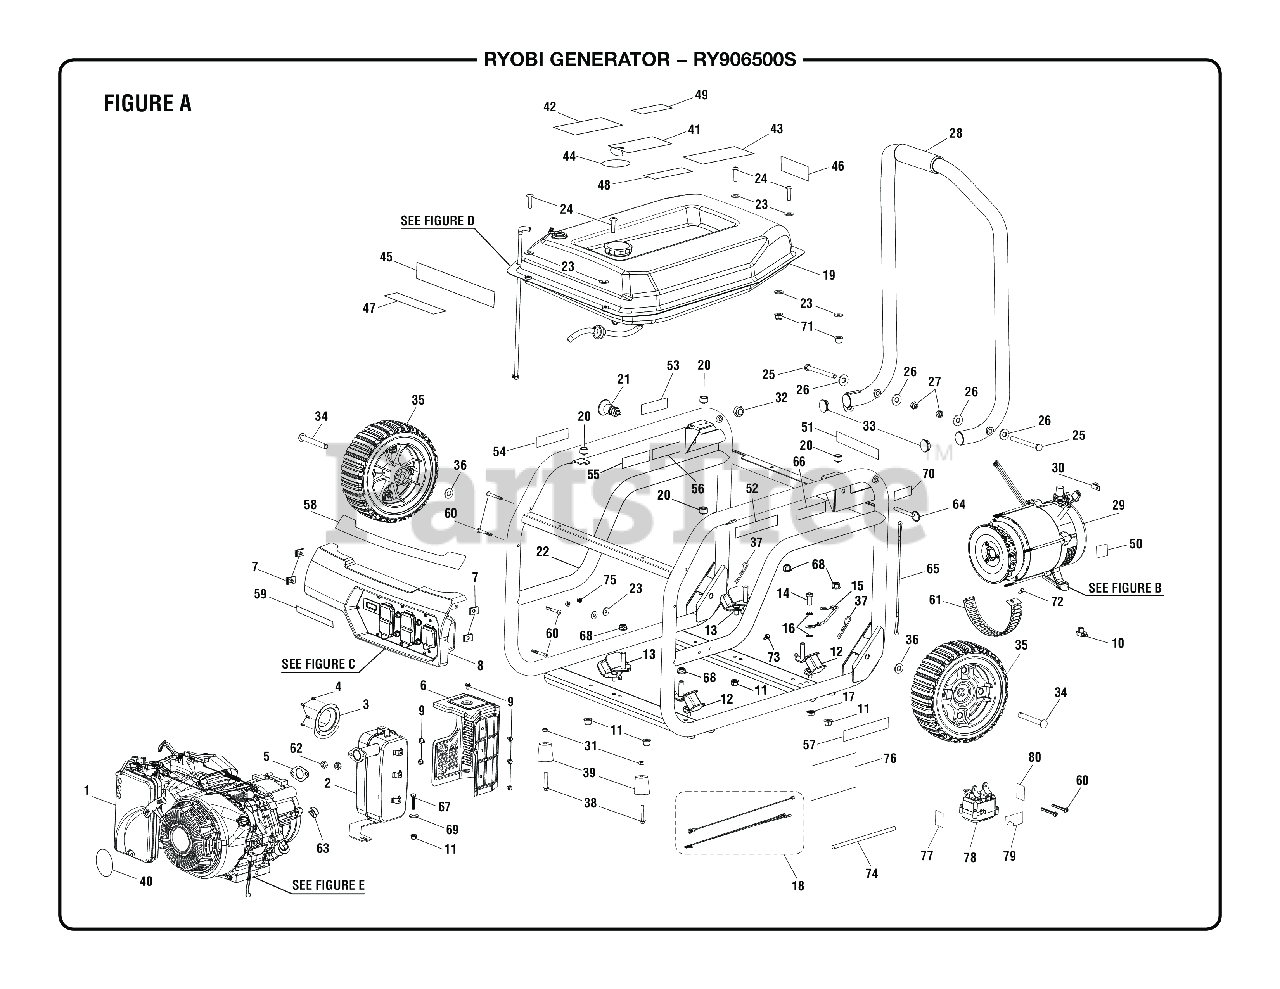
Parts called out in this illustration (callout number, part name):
3	Spark Arrester Screen
4	Screw (8-32 x 3/8 in., Pan Hd.)
5	Exhaust Gasket
6	Heat Shield
7	U-Clip (M6)
8	Control Panel Assembly
9	Bolt (M6 x 9 mm, Hex Flange Hd.)
10	Rubber Wire Protector
11	Lock Nut (M8 x 1.25 mm, Flange)
12	Engine Isolator (Large)
13	Engine Isolator (Right)
14	Bolt (5/16-18 x 3/4 in., Hex. Hd.)
15	Assembly, ground wire
16	Washer (5/16 in., External Star)
17	Flange Nut (5/16-18, Hex Hd.)
18	Wire Assembly
19	Fuel System
20	Handle Bumper
21	Quick Release Pin Assembly
22	Carrier Assembly
23	Washer (1/4 in., Type A)
24	Screw (1/4-20 x 1 in., T30 Torx Hd.)
25	Handle Pivot Pin (5/6-18 x 90 mm)
26	Washer ( 5/16 in.)
27	Lock Nut (5/16-18, Hex Hd.)
28	Handle Assembly
29	Generator Head Assembly
30	Ground Lug (5/16-24) (BM903600)
31	Lock Nut (M8 x 1.25)
32	Lock Nut (1/2-20, Hex)
33	End Cap (Handle)
34	Washer (M10)
35	Handle Isolator
36	Washer (OD19.75 x ID10.5 x 1t)
37	Hitch Pin (M3)
38	Bolt (M8 x 1.25 in., Flange Hex Hd.)
39	Foot Assembly
40	Engine Recoil Label
41	Warning Hangtag
42	Warning Label
43	CPSC (English) Label
44	Remove Cap Fuel Stabilizer Label (English)
45	Logo Label
46	UL Fire Warning Label Spark Arrestor)
47	Start Label
48	Fuel Stabilizer Label (French/Spanish)
49	No E85 Label
50	Ground Label Icon
51	Ground Warning Label
52	Risk of Fire Danger Label
53	Quick Release Pin Label
54	Exhaust Direction Label
55	Hot Surface and Exhaust Label
56	Fire Distance Label (Eng/Sp)
57	Engine Lubricant Label
58	Performance Label
59	Choke Label
60	Screw (M6 x 50 mm, T30 Torx Pan Hd. )
61	Fan Cover (Generator Head)
62	Hex Nut (M8 x 1.25, Special)
63	Plug (Generator Head)
64	Release Pin (5/16 x 2 in.)
65	Lanyard (3/16 in.)
66	Inquires Label (Ryobi)
67	Screw (M8 x 40 mm, Hex Hd.)
68	Lock Nut (5/16-18)
69	Washer (ID9 x OD25.4 x 2t)
70	Lock Pin Label
71	NYLON LOCK NUT (1/4-20)
72	Screw (M5 x 10 mm, Hex Hd.)
73	Bolt (M5 x 10 mm, Flange Hex Hd.)
74	Heat Shrink Tube
75	Lock Nut (M6 x 1 mm)
76	Auto Shut-Off Hang Tag
77	CO Shut-Off Label (English/Spanish)
78	CO Detector Shutdown Module
79	CO Monitor LED Label
80	CO Do Not Tamper (French/Spanish)
